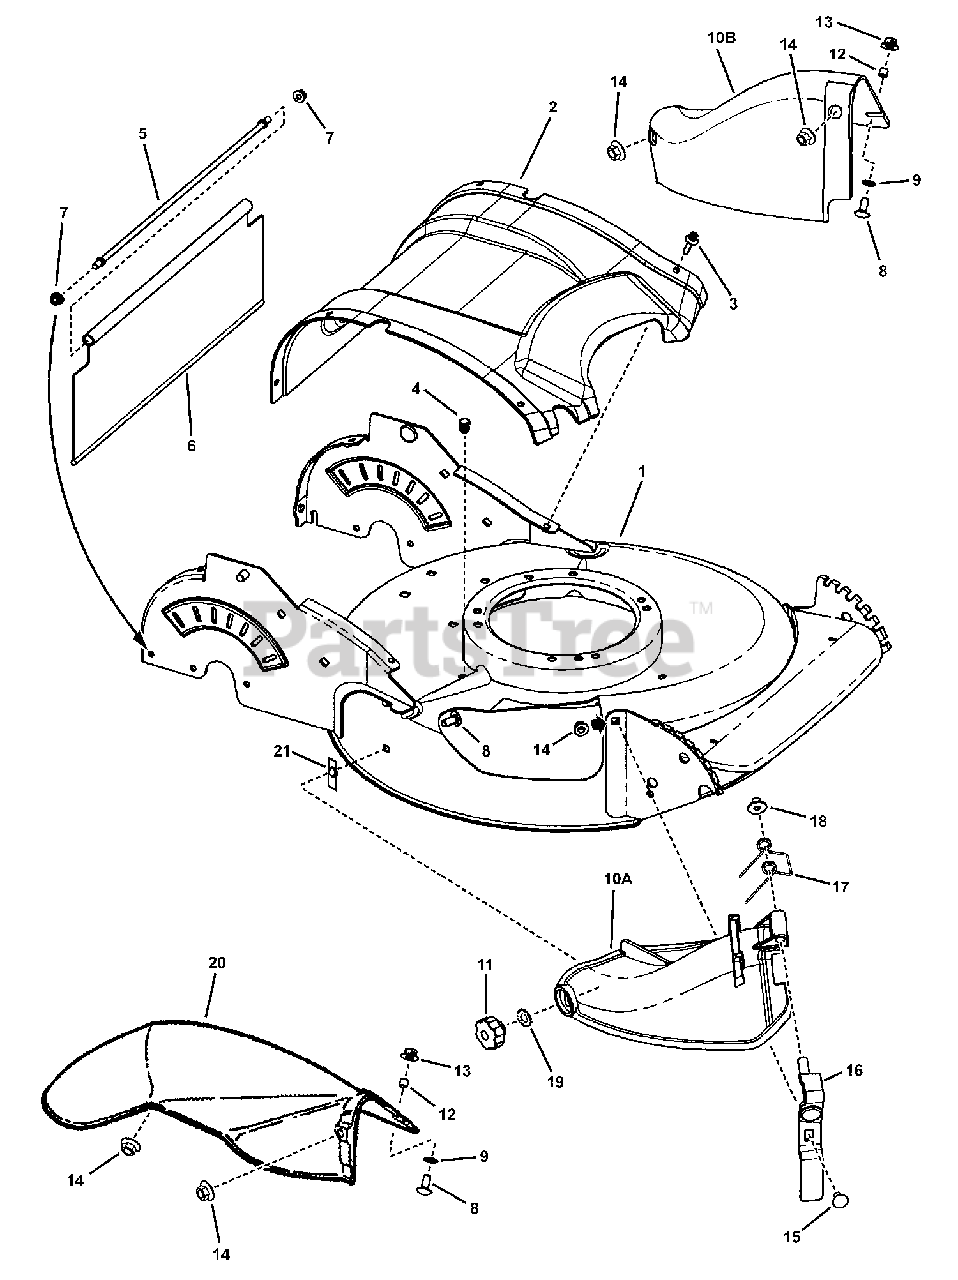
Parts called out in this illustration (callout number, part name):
1	WELDMENT, 21" Deck, 7 Position
2	REAR COVER, Belt/Transmission
3	SCREW, 7mm x 1 x .550 AB Point
4	PLUG, Hole (Polyethylene)
5	ROD, Trail Shield
6	SHIELD, Trail
7	NUT, 1/4-20 Hex Flange Lock
8	BOLT, 5/16-18 x 3/4" Short Square Neck Carriage, GR 5
9	BOLT RETAINER, 5/16- Black
10A	COVER, Mulching, No Tools
15	BOLT, 5/16-18 x 5/8" Short Square Neck Carriage, GR 5
16	WELDMENT, Hinge Pivot
17	SPRING, Torsion, Mulching Cover
18	PUSHNUT, 3/8"
19	WASHER, 5/16" Internal/External
20	CHUTE, 21 Side Discharge
21	NUT, 5/16-18 Speed
0180-10	TUBE, Lower
0180-20	SPRING, Clip
0180-40	WASHER, Rivet
